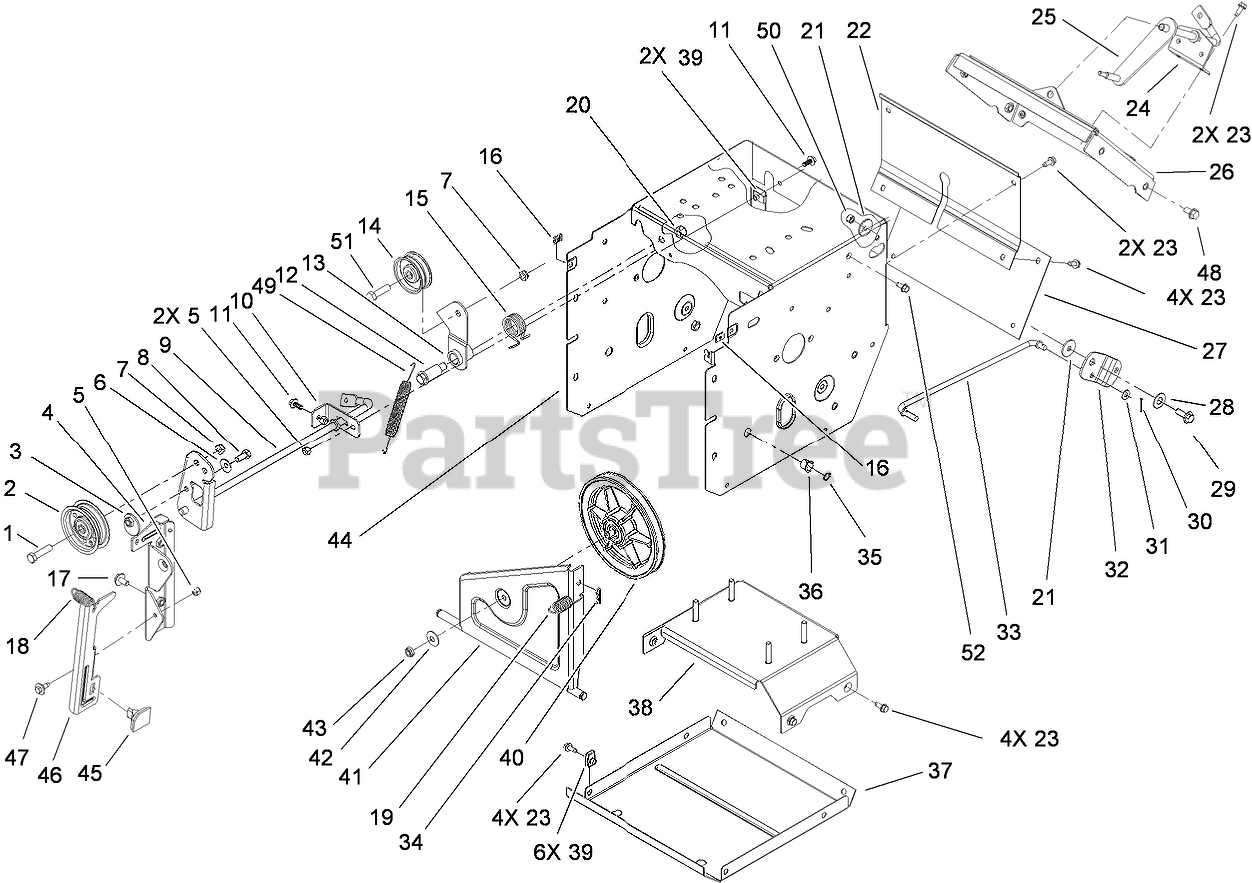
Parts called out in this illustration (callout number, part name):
1	SCREW-HH
2	PULLEY-IDLER
4	BRACKET-IDLER, IMPELLER
5	NUT-LOCK, NI
6	WASHER-BELLEVILLE
7	NUT-LOCK, NI
8	SCREW-HH
9	IMPELLER CLUTCH ASM
10	BRACKET-REAR, CLUTCH
11	SCREW-HHF
12	BOLT-SHOULDER
13	ARM-IDLER, TRACTION
14	PULLEY-IDLER
15	SPRING-TORSION
16	NUT-SPEED, U-TYPE
17	SCREW-HHF
18	SPRING-EXTENSION
19	SPRING-EXTENSION
20	NUT-LOCK, NI
21	WASHER-PIVOT
22	COVER-UPPER
23	SCREW-HWH
24	BRACKET-ROD, SHIFT
25	LEVER-CONTROL, TRACTION
26	SHIFT PLATE ASM
27	COVER-LOWER
28	WASHER
29	SCREW-SHOULDER
30	PIN-COTTER
31	WASHER-PLAIN
32	BELLCRANK-DRIVE
33	LINK-CONTROL, SPEED
34	PIN-COTTER
35	RING-RETAINING
36	BUSHING-NYLINER
37	PAN-BOTTOM
38	FRAME BRACE ASM
40	PULLEY-TRACTION
41	BRACKET-WHEEL, FRICTION
42	WASHER-BELLEVILLE
43	NUT-HEX
44	TRACTION FRAME ASM
45	PAD-BRAKE
46	ARM-BRAKE
47	SCREW-SHOULDER
48	SCREW-HWHTF
49	SPRING-EXTENSION
50	NUT-LOCK, NI
51	SCREW-HH
52	SCREW-HWH
